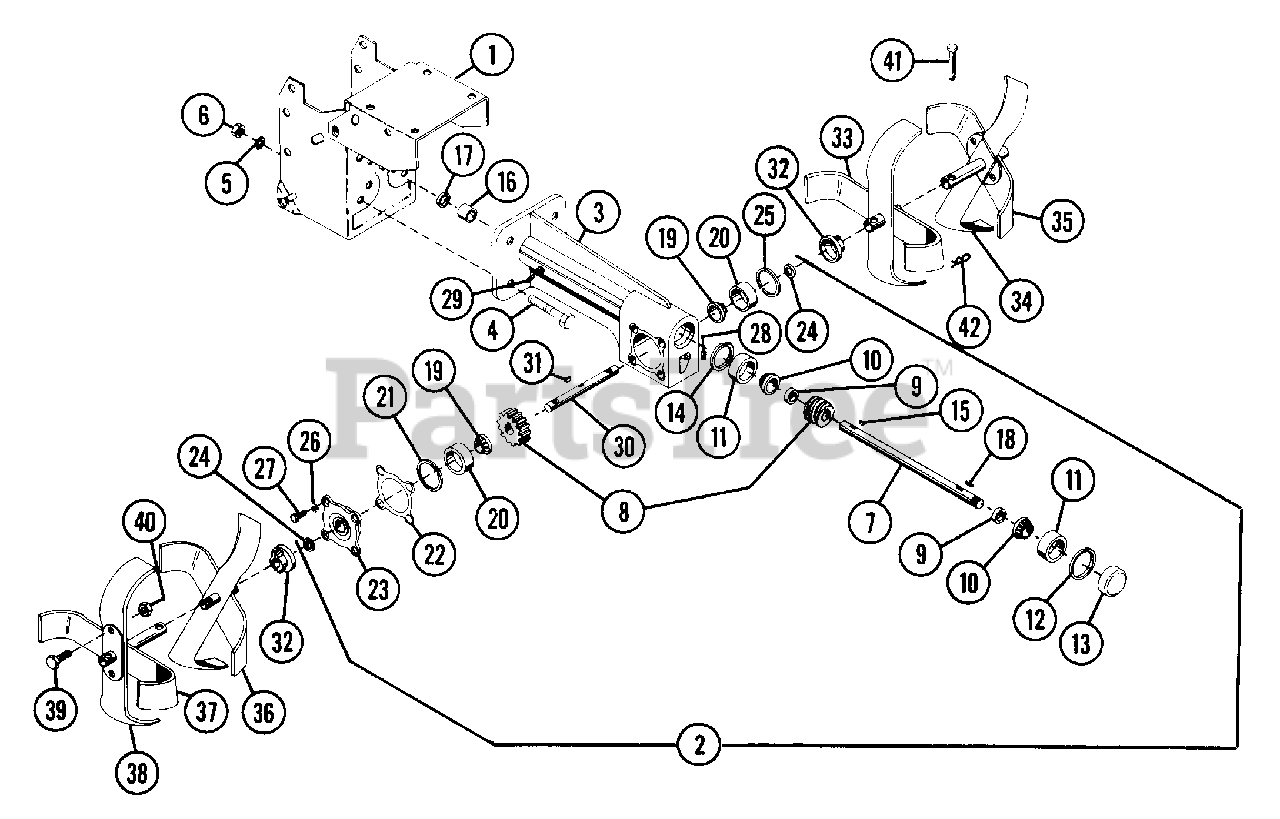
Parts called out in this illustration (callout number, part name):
1	FRAME
2	GEAR CASE - CAST IRON
3	WORM GEAR HOUSING
4	BLT-HEX .38-16X1.25 PL GR 2
5	WSHR-LK .375X.115 HVY PL
6	NUT-HEX .375-16
7	WORM SHAFT
8	WORM GEAR AND WORM - KIT
9	BSHG, SPCR .755X1.12X.50 PM
10	BRG-CONE .750X.61
11	BRG-CUP 1.781X.475
12	SNAP RING KIT
13	DUST CAP
14	RG-RTNG-INT 1.781X.062
15	KEY-WDRF .188X.875X.375 SAE11
16	BRG-NEEDLE .750X1.0X.62
17	SEAL .750X1.000X.125
18	KEY-SQ .188X1.0X.188 SAE 8630
19	BRG-CONE 1.0X.58
20	BRG-CUP1.980X.420
21	SNAP RING KIT
23	BEARING FLANGE
24	SEAL 1.000X1.980X.375
25	RG-RTNG-INT 1.969X.062
26	WSHR-LK .312X.097 PL HVY
27	BLT-HEX .31-18X.88 PL GR2
28	PIPE PLUG
29	BREATHER
30	TINE SHAFT
31	KEY-WDRF .25X.875X.375 SAE A
32	DUST CAP
33	L H INNER TINE SPOOL
34	L H OUTER TINE SPOOL
35	L H TURBO-TINE
36	R H INNER TINE SPOOL
37	R H OUTER TINE SPOOL
38	R H TURBO-TINE
39	BLT-HEX .44-14X1.00 GR5
40	NUT-LK-TOP .437-14 GR C PL
41	CLEVIS PIN
42	PIN-HAIR INT .08X.38X1.42 YWZC
